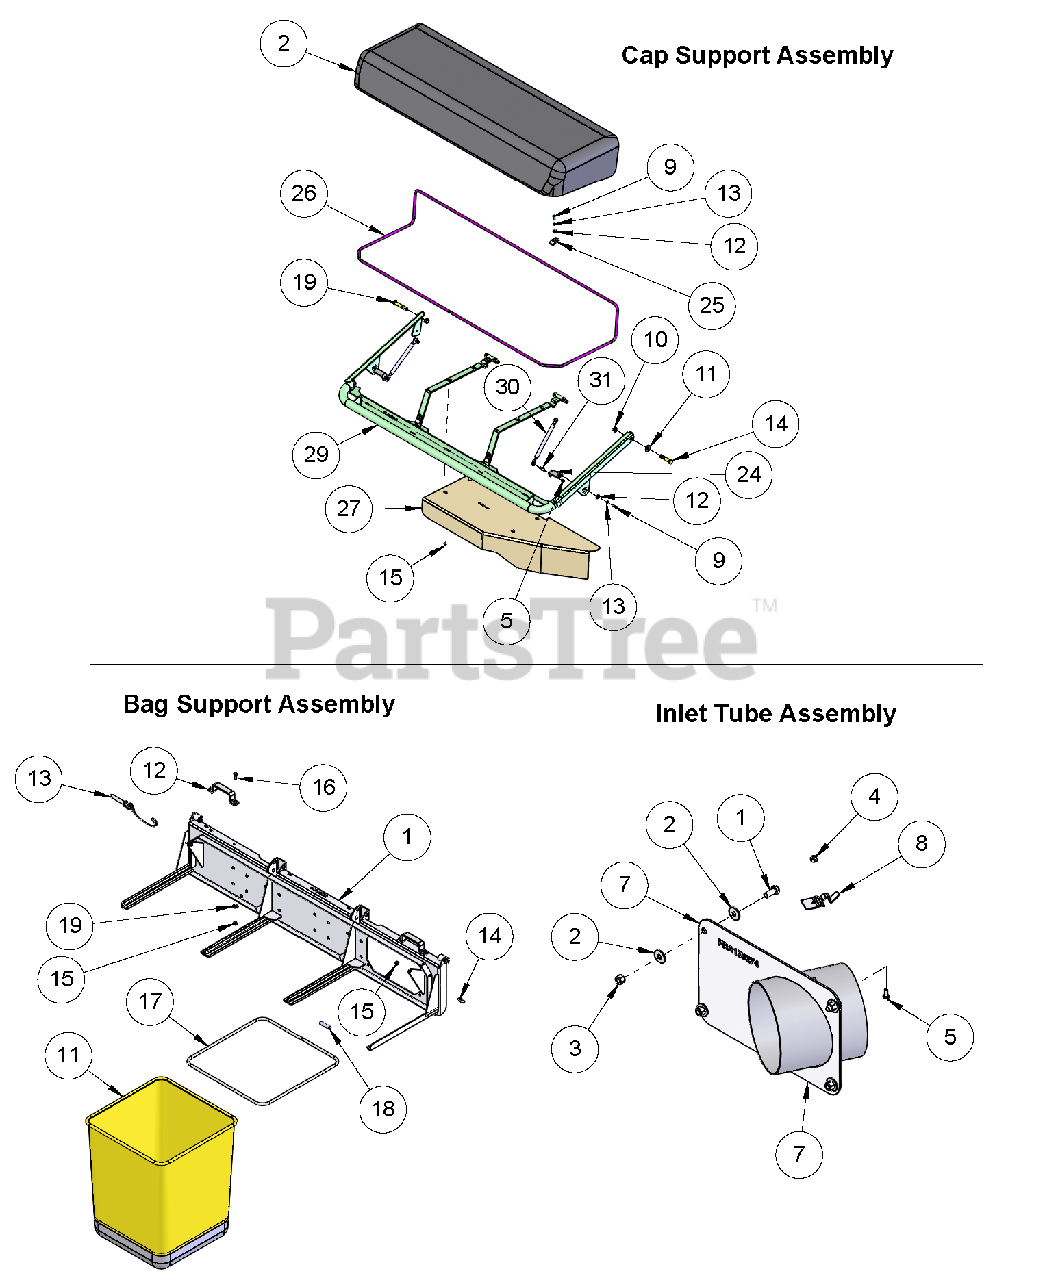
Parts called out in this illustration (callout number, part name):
1	CLOTH BAG
2	3 BAG FABRIC COVER W/J-STRIP
3	HOLE PLUG-ROUND
4	@BLT-HEX .31-18X.75 GR5 YWZC
5	@NUT-LK-NYL-FLG .31-18 YWZC
6	@WSHR-FL-STL.344X.688X.065YWZC
7	DETENT PIN W/LANYARD-1/2X2-1/2
8	RUBBER BUMPER
9	@BLT-HEX .25-20X.75 GR5 YWZC
10	@NUT-LK-NYL .50-13 YWZC
11	@WSHR-FL-STL.531X1.06X.095YWZC
12	@WSHR-FL-STL.281X.62X.065 YWZC
13	@WSHR-LK .25X.062 REG YWZC
14	@BLT-HEX .50-13X2.50 GR5 YWZC
15	@BLT-HEX .25-20X.50 GR5 YWZC
16	@SCR-MCH 10-24X.50 HWH YWZC
17	@NUT-LK-NYL 10-24 W/INSRT YWZC
18	SPRING CLIP
19	@BLT-HEX .50-13X3.00 GR5 YWZC
20	TUBE, PLASTIC 1/2" OD X 3/8 ID
21	BAG HANDLE
22	INLET TUBE (SHORT)
23	GRASS BAG FRAME
24	BKT,GAS CYLINDER MOUNT
25	BKT,MOUNT-SINGLE HOLE
26	AIR DOME FRAME 3/8 ROD
27	3-BAG DEFLECTOR
28	3-BAG SUPPORT MOUNT
29	2-BAG CAP SUPPORT(OFFSET SUPT)
30	GAS CYLINDER
31	BALL STUD
